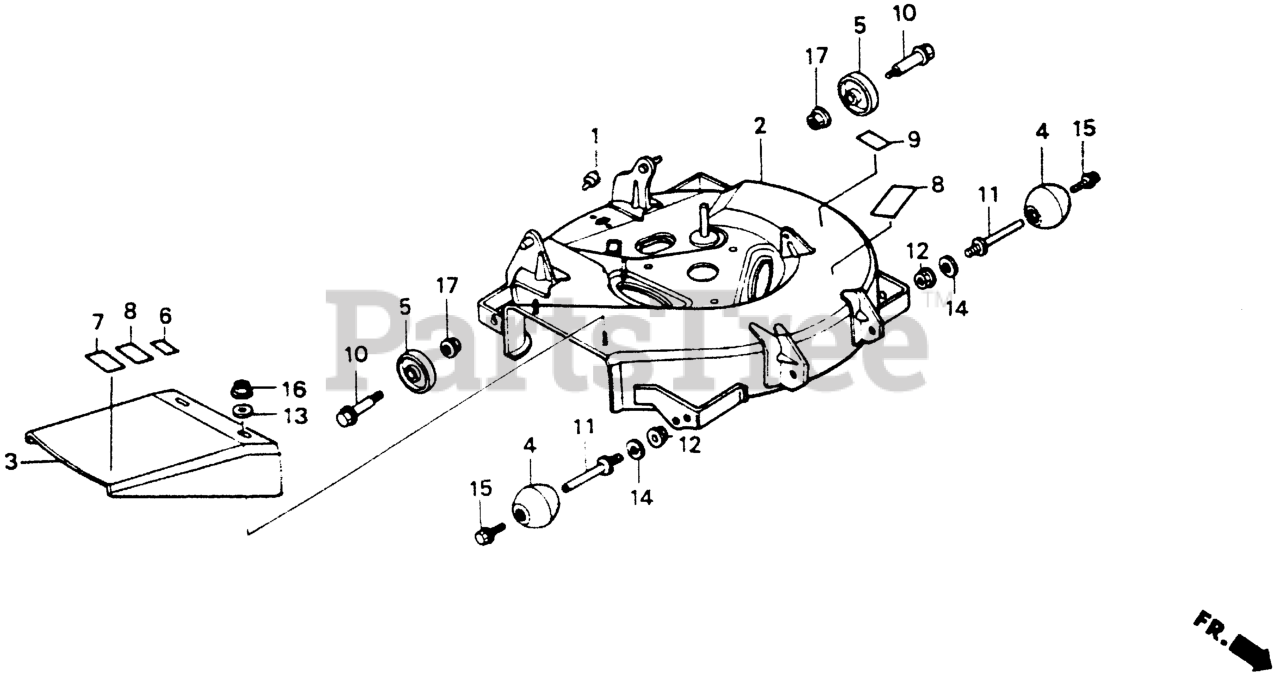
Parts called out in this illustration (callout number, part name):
1	RUBBER, STOPPER
2	HOUSING, CUTTER
3	ADAPTER, DISCHARGE *NH190M* (VINTAGE GRAY METALLIC) (NOT AVAILABLE)
4	ROLLER, ANTI-SCALP
5	ROLLER, RR. ANTI-SCALP
6	MARK, INCH SIZE (30)
7	LABEL B, WARNING (ENGLISH)
8	LABEL A, WARNING (ENGLISH)
9	LABEL D, CAUTION (ENGLISH)
10	BOLT, ANTI-SCALP ROLLER
11	SHAFT, ANTI-SCALP ROLLER
12	NUT, SELF-LOCK (12MM)
13	WASHER, PLAIN (8MM) (NOT AVAILABLE)
14	WASHER, THRUST (12MM)
15	BOLT-WASHER (8X16)
16	NUT, FLANGE (8MM)
17	NUT, FLANGE (10MM)
